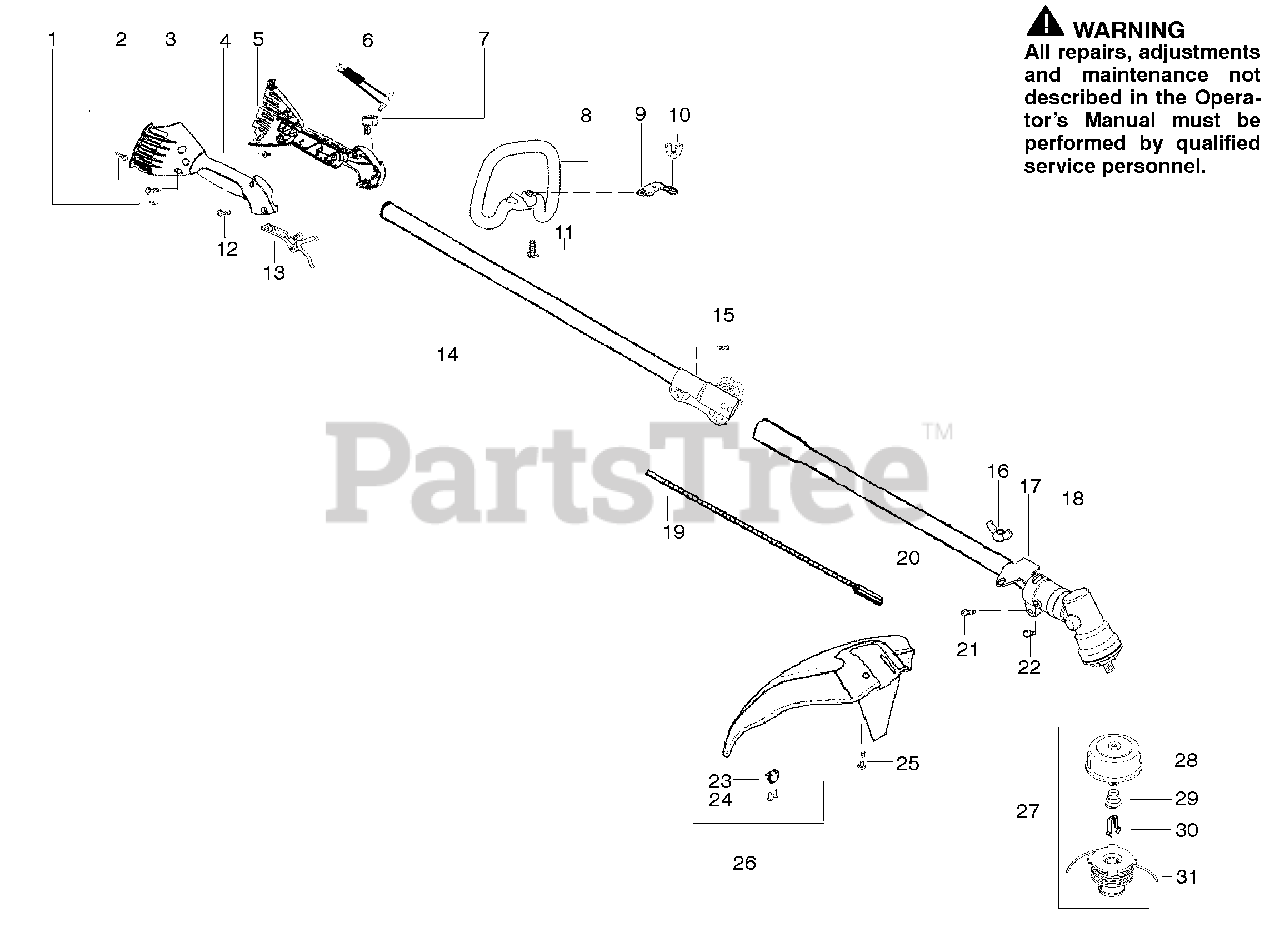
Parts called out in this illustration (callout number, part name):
1	Screw-alignment
3	Hsg.-Throttle right
4	Screw-Cable Retention
5	Hsg.-Left throttle
6	Assy-Wire
7	Kit-Switch
8	Handle-Assist
9	Clamp-Handle
10	Wingnut
13	Lever-Throttle
14	Assy-Upper Shaft
16	Wingnut
17	Bracket-Shield
19	Shaft-Flex (lower)
20	Assy-Lower Shaft
23	Limiter-Line
26	Kit-Shield Assy.
27	Accy-Cutting Head
28	Assy-Hub/Arbor
29	Spring-Return
30	Retainer-Spool
31	Accy-Wound Spool
